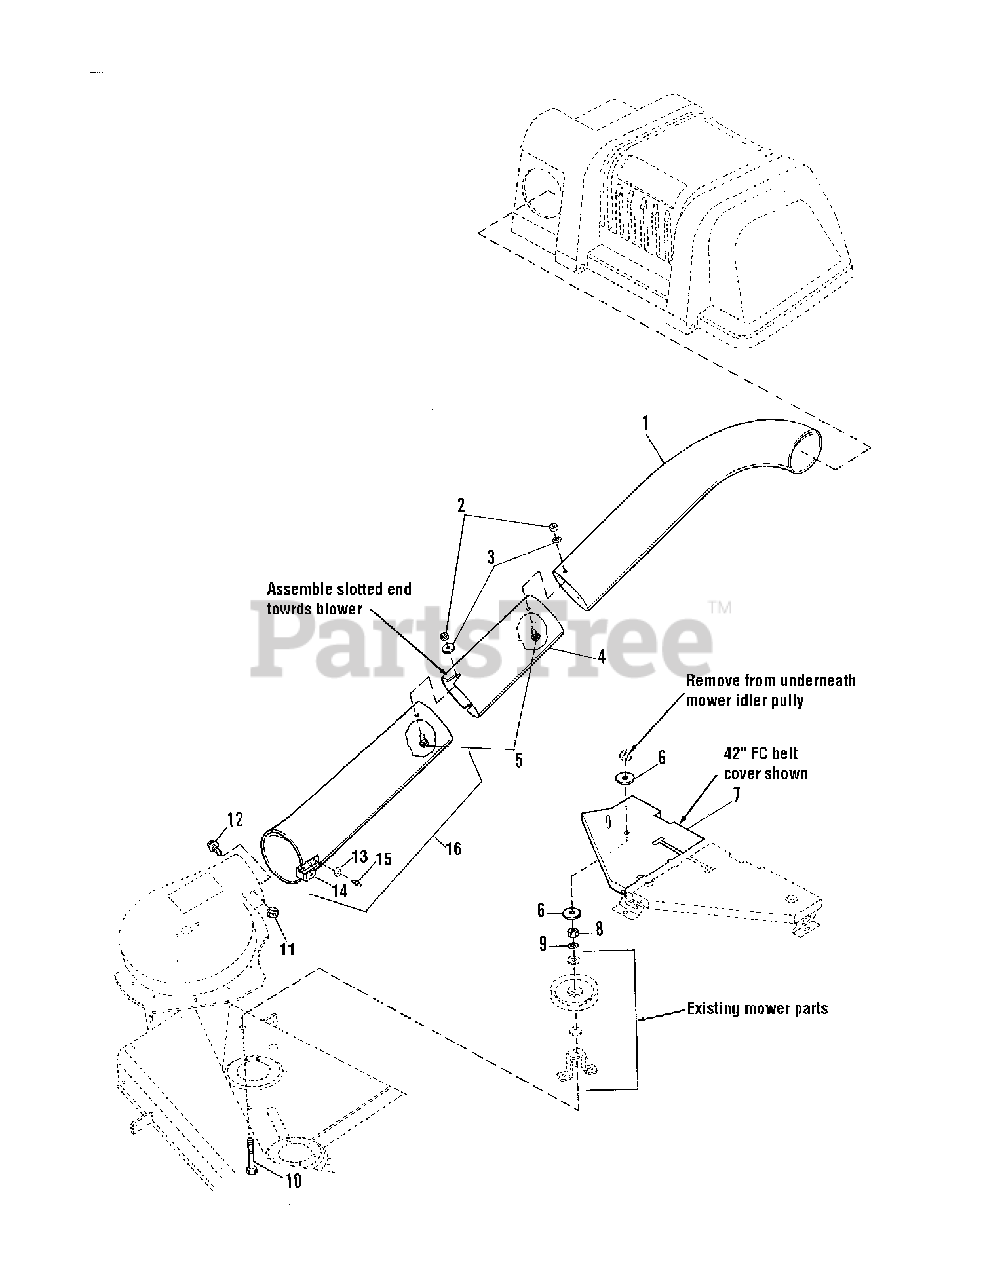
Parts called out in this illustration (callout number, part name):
1	TUBE, Upper
2	NUT, Hex, Nylock #10-24
3	WASHER, Flat
4	TUBE, Middle
5	SCREW, Truss Head, #10-24 x 3/4
6	WASHER
7	COVER ASSEMBLY, Belt
8	NUT, Hex, 3/8-16
9	LOCKWASHER, 3/8
10	CAPSCREW, Hex Head, 3/8-16 x 2-1/4
11	NUT, Hex Flange, 1/4-20
12	CARRIAGE BOLT, 1/4-20 x 3/4
14	CLIP, Spring
16	TUBE ASSEMBLY, Lower (Inc. Ref. Nos. 13, 14, & 15)
